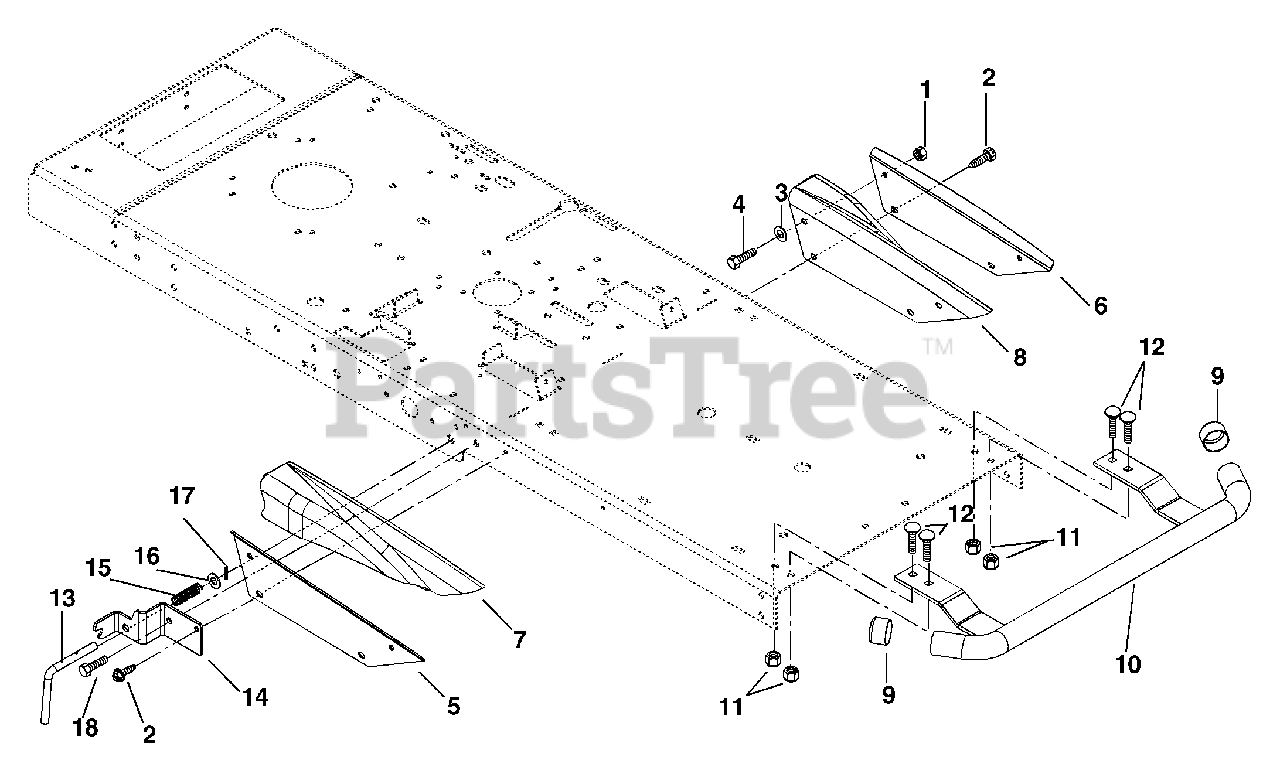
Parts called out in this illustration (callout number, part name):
1	Nut-Locking-Nylon .312-18 Grade 5
2	Screw-Tapping .312-18 x .75 Grade 5
3	Washer-Flat-Steel .344 x .688 x .065
4	Bolt-Hex .312-18 x .75 Grade 5
5	Bracket-Rail Support-Right Hand
6	Bracket-Rail Support-Left Hand
7	Rail-Side-Right Hand
8	Rail-Side-Left Hand
9	Cap-Sleeve
10	Weldment-Bumper
11	Nut-Locking-Nylon .375-16 Grade 5
12	Bolt-Round Head Square Neck .375-16 x 1.00 Grade 5
13	Pin-Index
14	Bracket-Stop
15	Spring-Compression
16	Washer-Flat-Steel .531 x 1.06 x .095
17	Pin-Roll .156 x 1.00
18	Bolt-Hex .38-16 x 1.00 Grade 5
